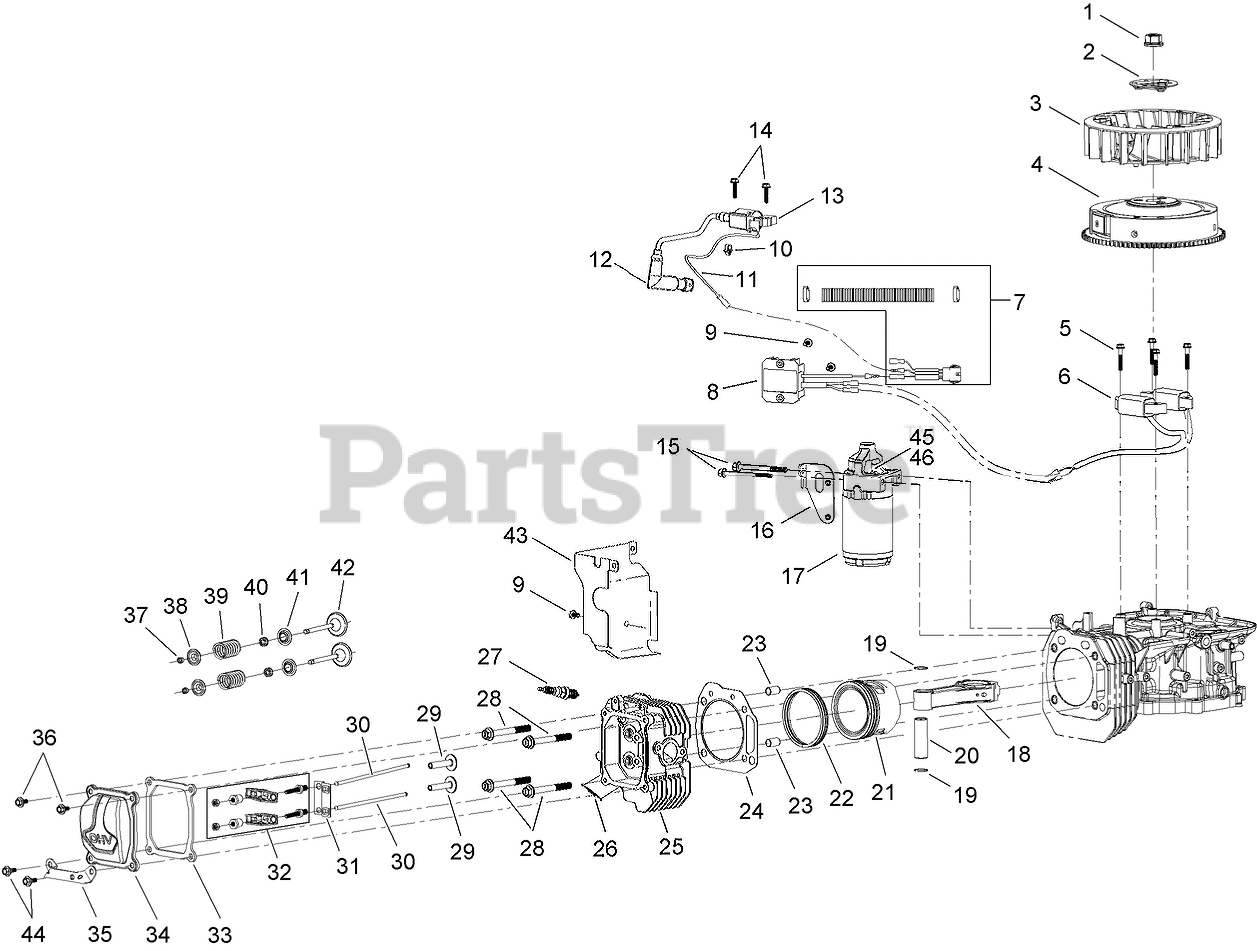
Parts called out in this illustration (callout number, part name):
1	NUT-FLANGE
2	PULLEY-STARTER
3	FAN-COOLING
4	FLYWHEEL ASM
5	SCREW-HHF
6	CHARGE COIL ASM
7	WIRE HARNESS KIT
8	REGULATOR-VOLTAGE
9	SCREW-HHF
10	CLAMP-WIRE
11	WIRE-KILL, IGNITION
12	BOOT-PLUG, SPARK
13	IGNITION COIL ASM
14	SCREW-HHF
15	SCREW-HHF
16	BRACKET-STARTER
17	STARTER-ELECTRIC
18	CONNECTING ROD ASM
19	RING-RETAINING, PISTON PIN
20	PIN-PISTON
21	PISTON
22	RING SET
23	PIN-DOWEL
24	GASKET-CYCLINDER
25	HEAD-CYLINDER
26	GASKET-EXHAUST
27	PLUG-SPARK
28	SCREW-HHF
29	LIFTER-VALVE
30	ROD-PUSH
31	PLATE-GUIDE, PUSH ROD
32	ROCKER ARM KIT
33	GASKET-COVER, VALVE
34	COVER-VALVE
35	BRACKET-MUFFLER
36	SCREW-SHOULDER, HHF
37	KEEPER-VALVE
38	RETAINER-SPRING, VALVE
39	SPRING-VALVE
40	SEAL-STEM, VALVE
41	SEAT-SPRING, VALVE
42	VALVE SET
43	SHIELD
44	SCREW-SHOULDER, HHF
45	STARTER REPAIR KIT
46	PINION
